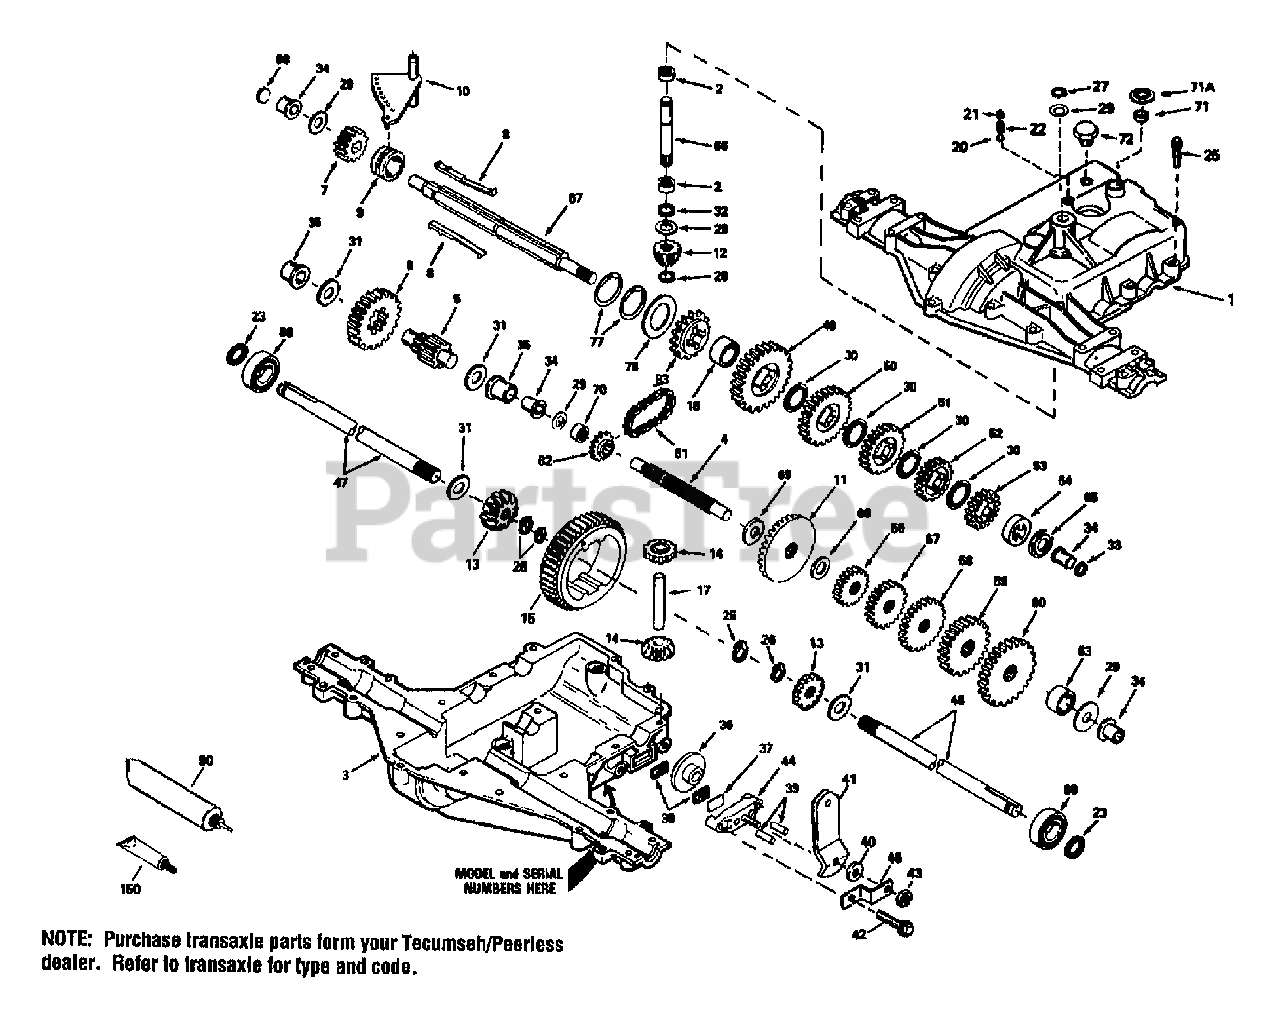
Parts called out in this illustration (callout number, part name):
1	COVER, TRANSAXLE
2	NEEDLE BEARING
4	COUNTERSHAFT
7	SPUR GEAR
8	SHIFT KEY
10	ROD & FORK
11	BEVEL GEAR
12	INPUT PINION
13	BEVEL GEAR
14	BEVEL GEAR
15	RING GEAR
17	DRIVE PIN
22	SPRING
23	SEAL
26	RET RING
27	RET RING
28	RET RING
29	WASHER
30	WASHER
32	O RING
33	SQUARE CUT RING
34	BUSHING
37	BRAKE PAD PLATE
39	DOWEL PIN
41	BRAKE LEVER
59	SPUR GEAR
60	SPUR GEAR
66	INPUT SHAFT
67	BRAKE SHAFT
81	ROLLER CHAIN
82	SPROCKET
